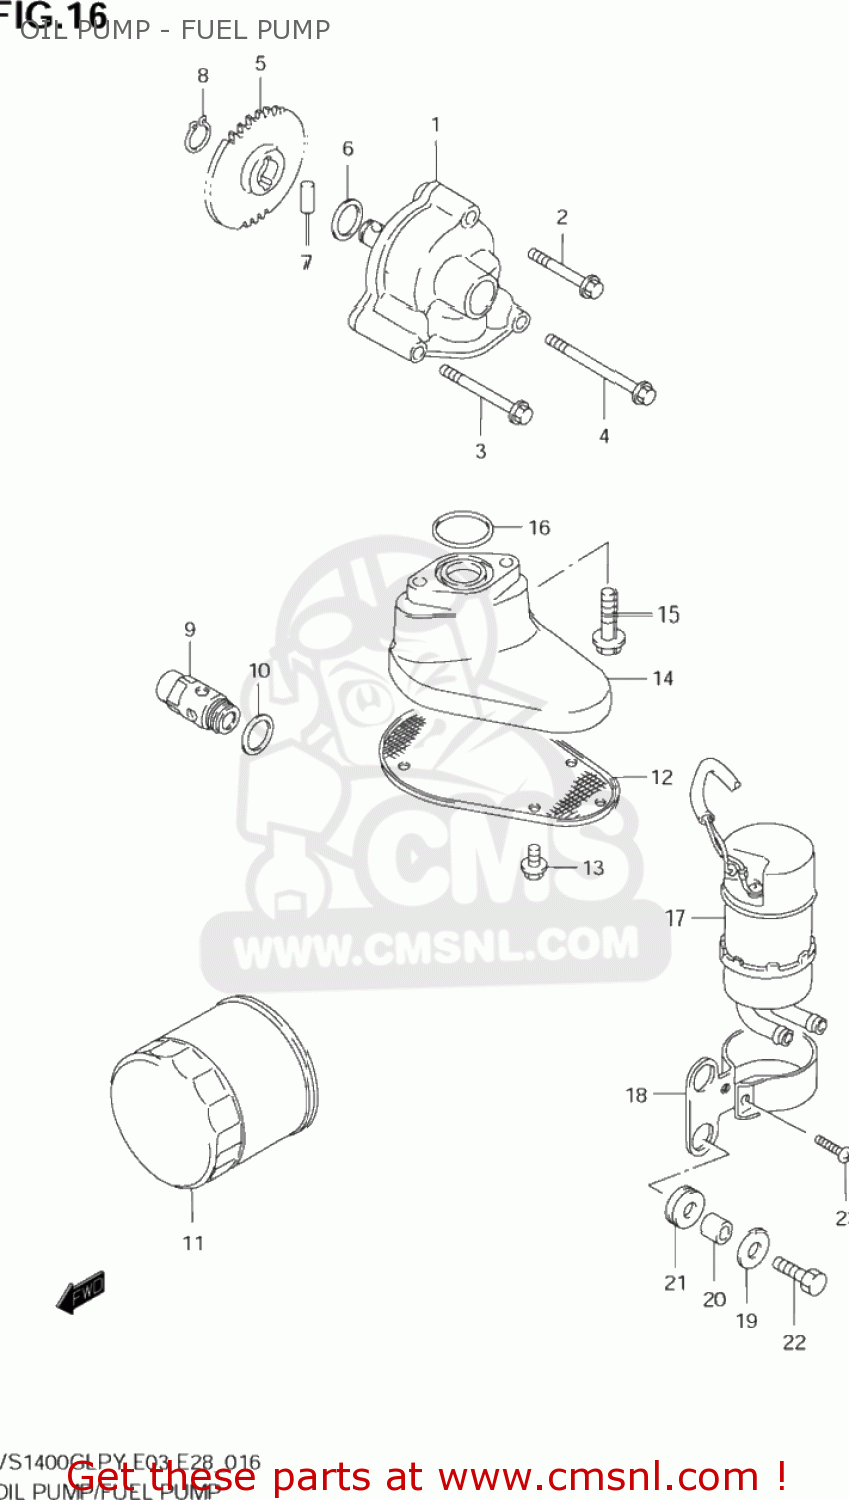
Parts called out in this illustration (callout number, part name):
1	PUMP ASSY,ENGINE OIL
2	BOLT
3	BOLT
4	BOLT
5	GEAR,OIL PUMP DRIVEN
6	SHIM
7	PIN(5X18)
8	CIRCLIP,12 MM
9	VALVE ASSY,OIL RELIEF
10	GASKET(16X22X2) (NAS)
11	FILTER ASSEMBLY,ENGINE OIL
12	STRAINER,ENGINE OIL
13	BOLT
14	HOLDER,OIL STR
15	BOLT
16	O RING(D:3.1,ID:22.7)
17	PUMP ASSY,FUEL
18	BRACKET,FUEL PUMP
19	WASHER(6.5X20X1.6)
20	SPACER(6.5X10X9.4)
21	CUSHION
22	BOLT
23	SCREW
